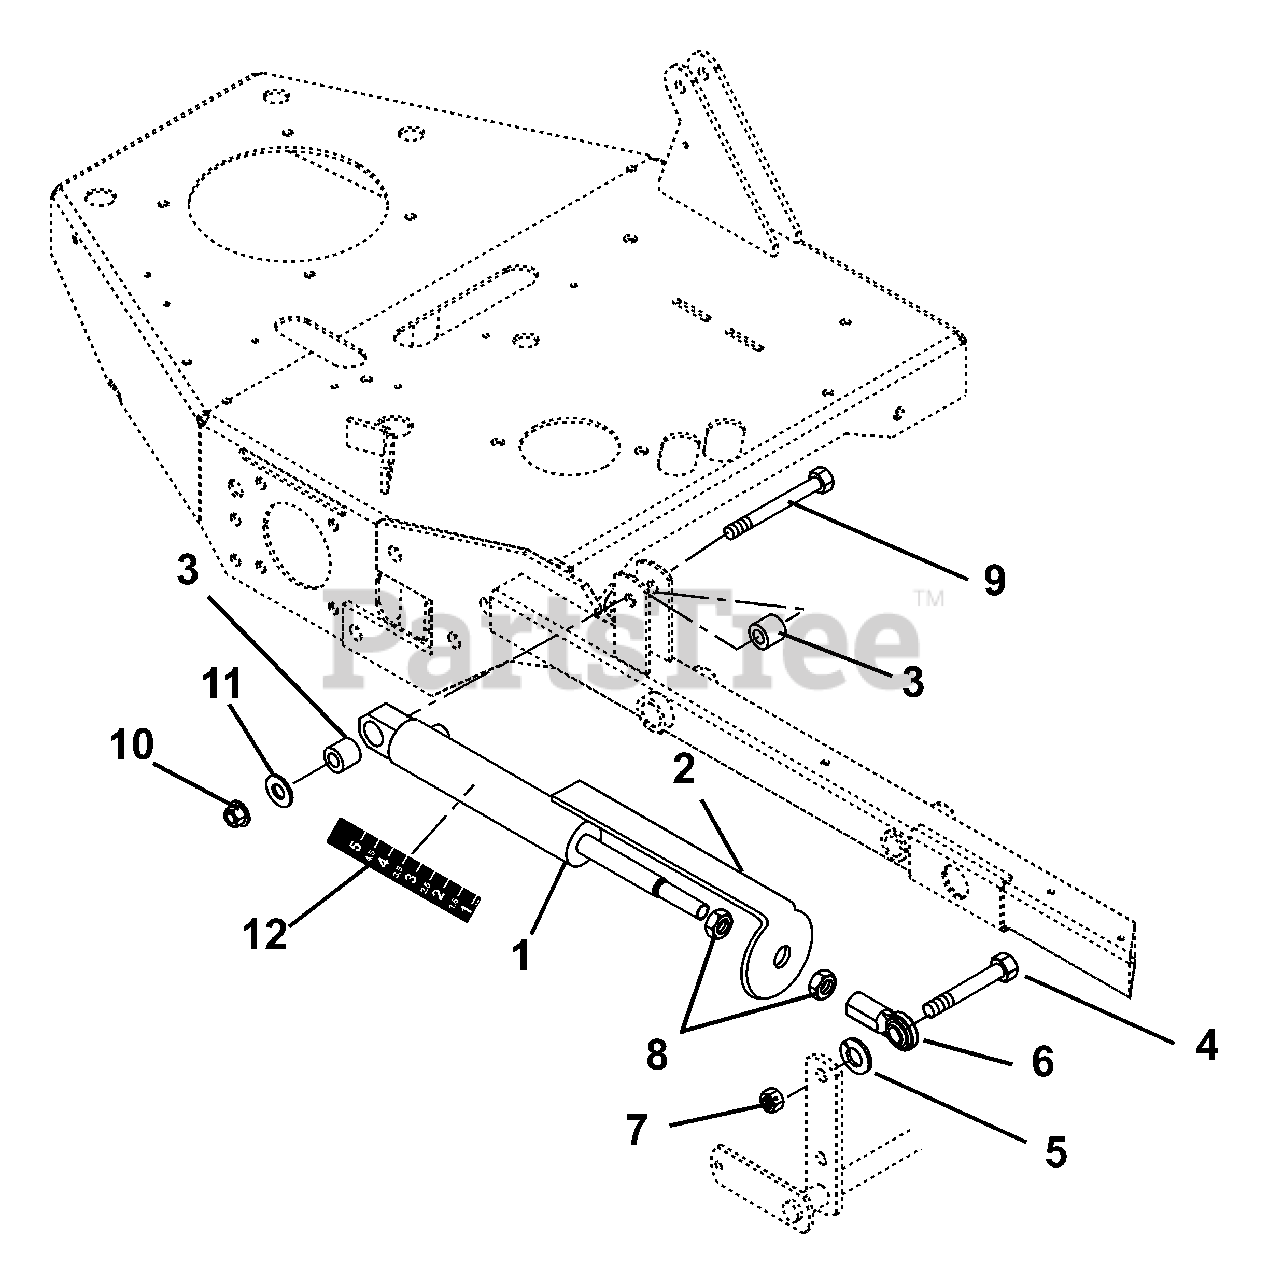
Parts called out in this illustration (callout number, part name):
1	Cylinder, Lift
2	Strap-Height of Cut Indicator
3	Bushing .516 x 1.00 x 1.05
4	Bolt-Hex .62-11 x 2.25 Grade 8
5	Washer-Lock .62 x .156
6	Rod End-Right Hand-Female .63
7	Nut-Locking-Center .62-11
8	Nut-Jam .63-18
9	Bolt-Hex .50-13 x 4.00 Grade 5
10	Nut-Locking-Top-Flange .50-13
11	Washer-Flat-Steel .515 x 1.625 x .25
12	Decal, Height of Cut
